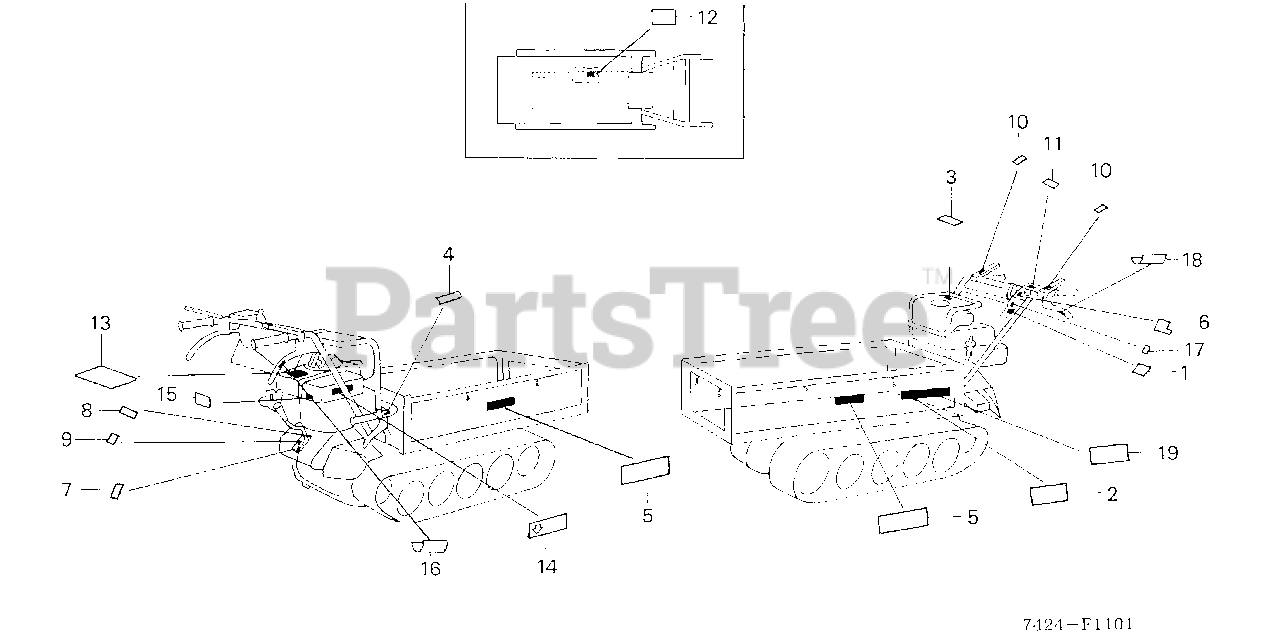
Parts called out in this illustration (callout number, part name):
1	EMBLEM
2	MARK, CARRIER CAUTION (ENGLISH)
3	LABEL, FUEL CAUTION (ENGLISH)
4	MARK, LOCK LEVER
5	MARK, SEAT
6	MARK, ENGINE SWITCH (ENGLISH)
7	MARK, POSITION INDICATION (ENGLISH)
8	MARK, POSITION INDICATION
9	MARK, POSITION INDICATION
10	MARK, CLUTCH INDICATION (ENGLISH)
11	LABEL C, CAUTION
12	MARK, DUMP LOCK
13	LABEL A, CAUTION (ENGLISH)
14	MARK, AIR CLEANER CAUTION (ENGLISH)
15	MARK, CHOKE
16	MARK, R. SIDE CLUTCH (ENGLISH)
17	MARK, THROTTLE
18	MARK, L. SIDE CLUTCH (ENGLISH)
19	LABEL, MAXIMUM WEIGHT CAUTION
